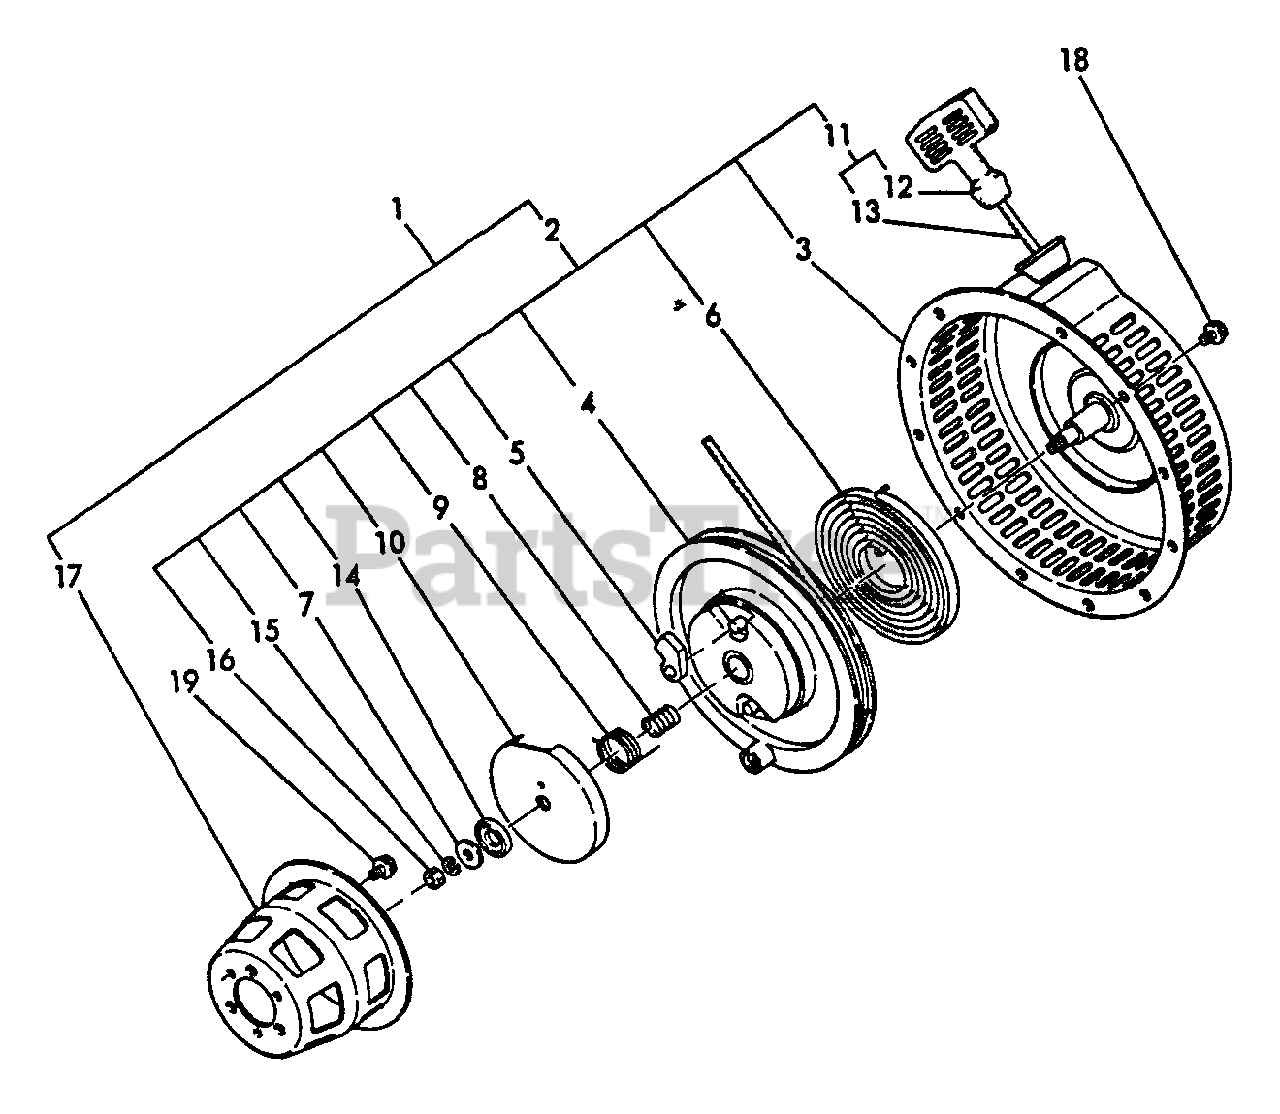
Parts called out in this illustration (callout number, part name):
1	STARTER ASSY
2	STARTER ASSY
3	CASE, STARTER
5	RATCHET
6	SPRING
7	WASHER, THRUST
8	SPRING, FRICTION
9	SPRING, RETURN
10	PLATE, FRICTION
11	STARTER ROPE ASSY
12	KNOB, STARTER
13	ROPE, STARTER
14	WASHER, THRUST
15	LOCKWASHER - 6
17	REEL, ROPE
18	BOLT - 6X8 -- PLATED
19	BOLT - 6X12 -- PLATED
